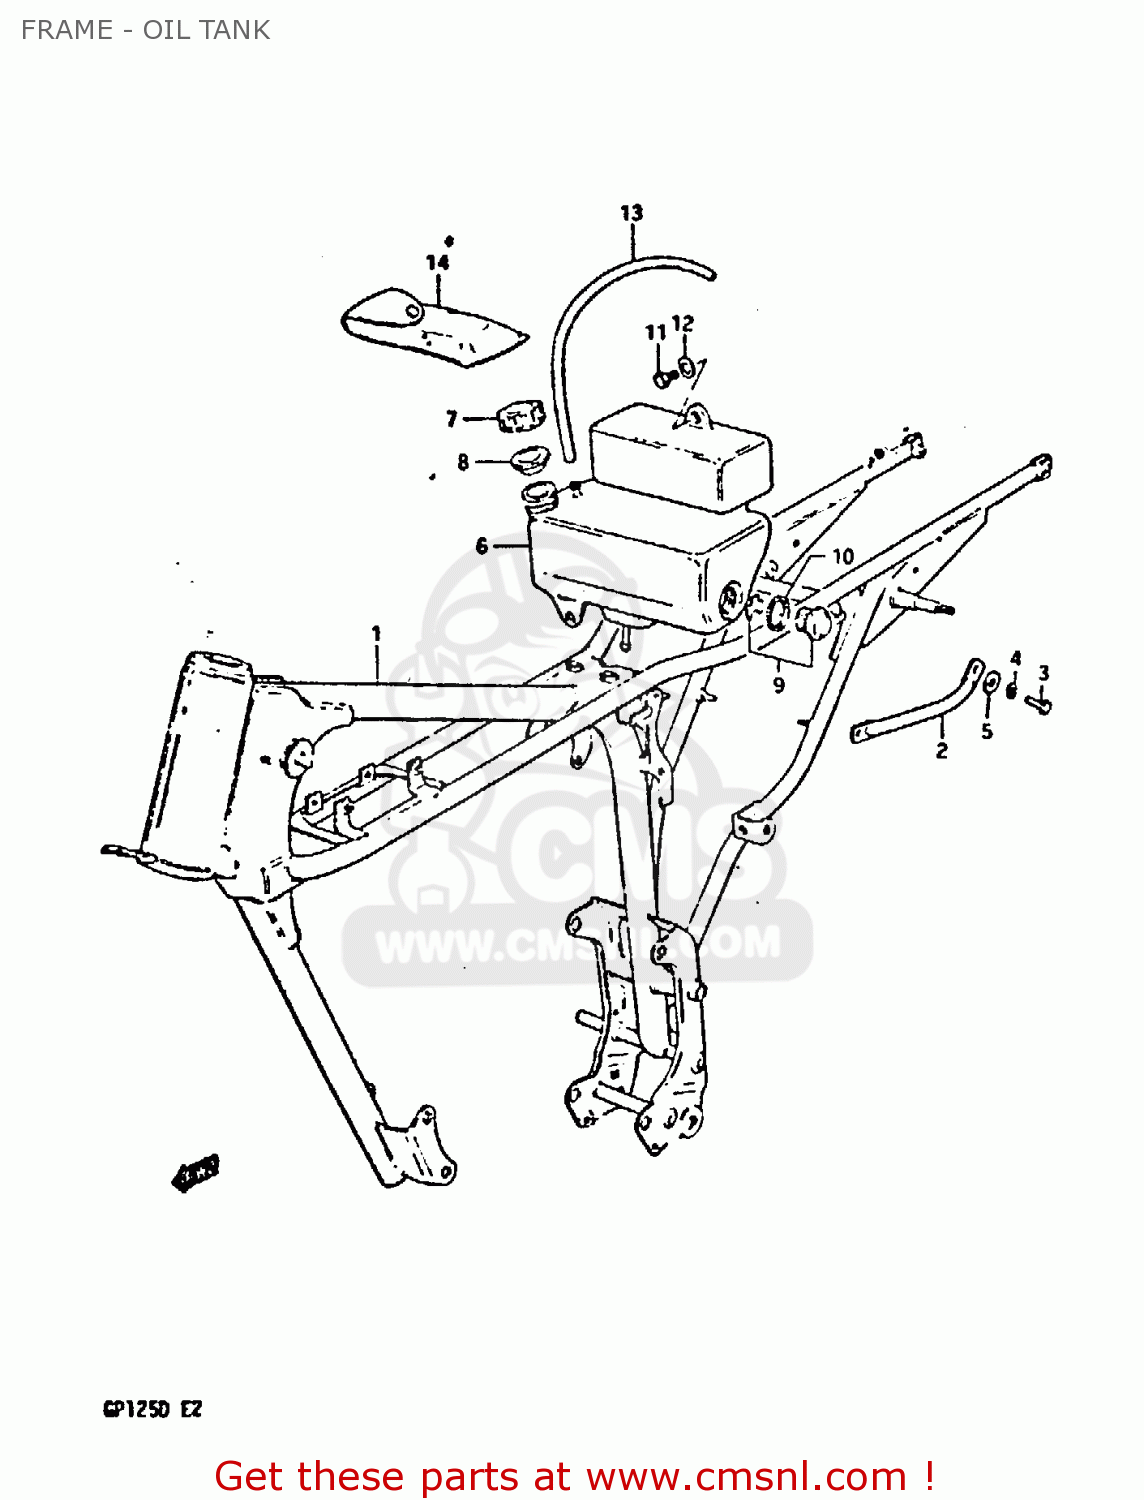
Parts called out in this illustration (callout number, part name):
1	FRAME (BLACK)
2	GRIP, FRAME HANDLE
3	BOLT 8X12
4	LOCK WASHER
5	WASHER
6	TANK,OIL
7	CAP,OIL TANK
8	GASKET,OIL TANK CAP (NAS)
9	LENS SET,OIL LEVEL
10	GASKET (NAS)
11	BOLT, UPPER
12	WASHER
13	HOSE
14	TOOL SET
